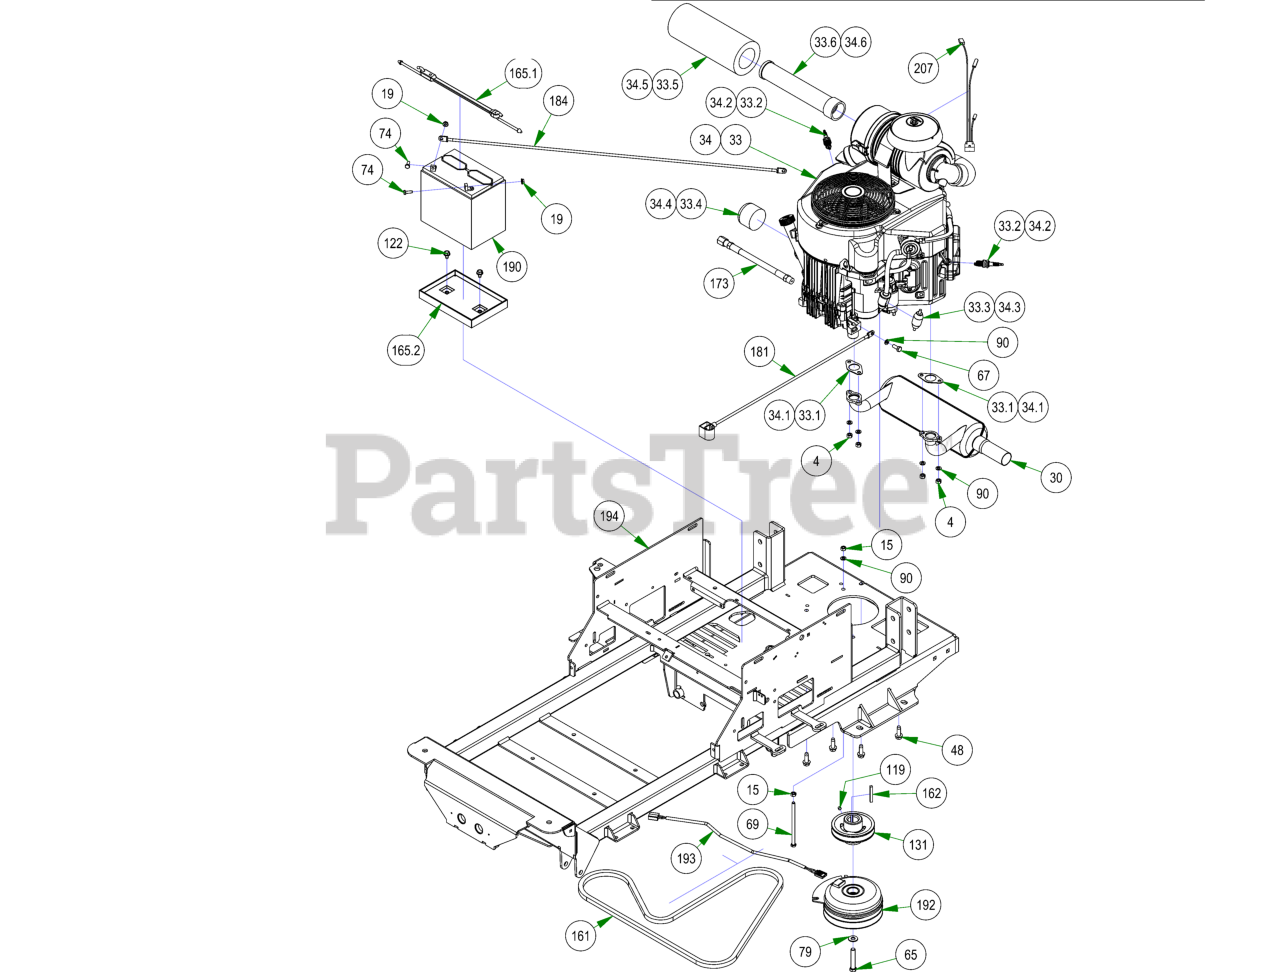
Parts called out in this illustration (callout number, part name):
4	M8-1.25 DIN 934 HEX NUT (CL.8) ZINC
15	5/16-18 HEX NUT ZINC
19	1/4-20 HEX SERRATED FLANGE NUT HARD/ZINC
30	Kawasaki Muffler 1251
33	FX691 Kawasaki-2016 Compact Outlaw
33.1	Exhaust Gasket
33.2	Spark Plug - Kawasaki
33.3	Universal Inline Fuel Filter
33.4	Oil Filter
33.5	Canister Air Filter- Outer
33.6	Canister Air Filter- Inner
34	FX-730 Kawasaki
34.1	Exhaust Gasket
34.2	Spark Plug - Kawasaki
34.3	Universal Inline Fuel Filter
34.4	Oil Filter
34.5	Canister Air Filter- Outer
34.6	Canister Air Filter- Inner
48	3/8-16 X 1-1/8 HEX WASHER UNSLOT SERRATED (TRI-LOB) TRS ZINC YELLOW
65	7/16-20 X 2-1/2 HEX Bolt GR 8 W/ Patch
67	M8-1.25 X 20MM DIN 933 HEX TAP BOLT (CL 8.8) ZINC
69	5/16-18 X 5-1/2 HEX CAP SCREW (GR.5) ZINC
74	1/4-20 X 3/4 HEX CAP SCREW (GR.5) ZINC
79	3/8 FLAT WASHER USS (1" OD) ZINC
90	5/16 SPLIT LOCKWASHER ZINC
119	5/16-24 X 1/4 SOCKET SET SCREW (CUP PT) PLAIN
122	5/16-18 X 1/2 HWH unslot (F) tcs zinc
131	4 3/4 Motor Pulley
161	75.8" Pump Belt
162	1/4 X 2 SQ MACHINERY KEY 1018 STL PLAIN
165	2023 Battery Hold Down Assembly Strap
165.1	2023 Rubber Battery Hold Down Strap
165.2	Battery Tray
173	Oil drain Hose
181	24 inch Black Cable – MZ/ZT
184	36" Red Battery Cable
190	SP-35 Battery
192	Clutch Assembly
193	Clutch Pigtail
194	2023 Maverick Frame - Painted
207	Harness Adaptor
